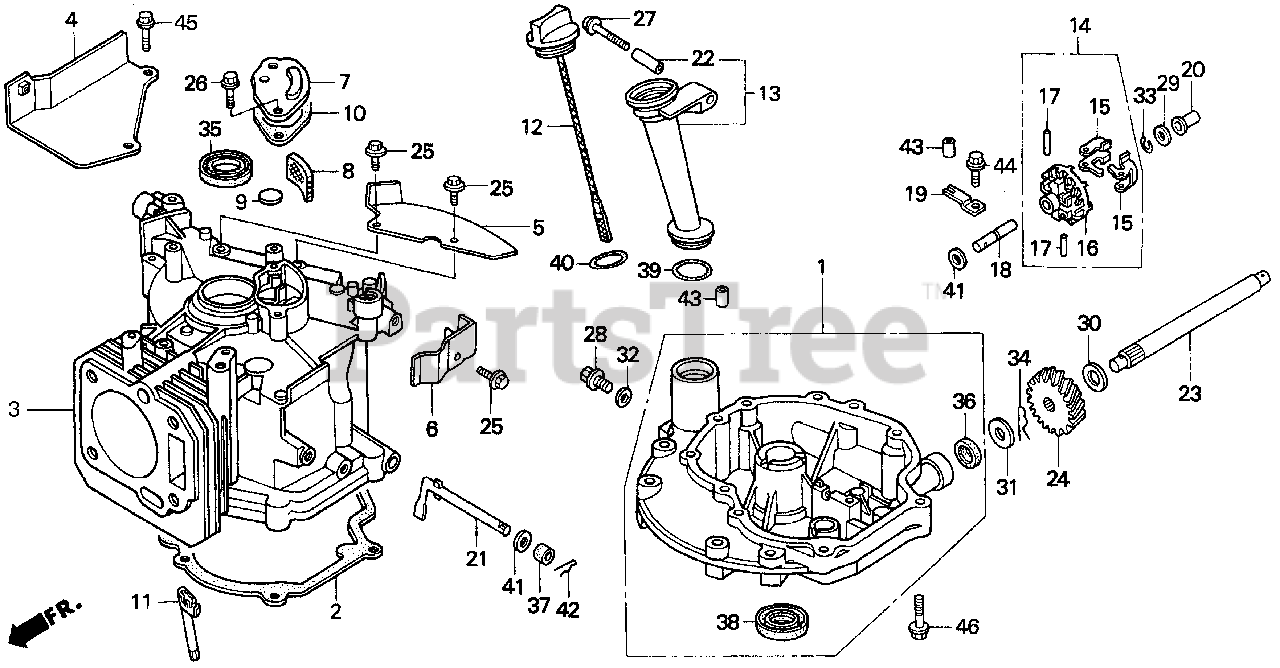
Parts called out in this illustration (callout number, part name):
1	PAN ASSY., OIL
2	GASKET, OIL PAN (HPE)
3	CYLINDER
4	PLATE, GUIDE
5	PLATE A, GUIDE
7	CAP, BREATHER CHAMBER
8	FILTER, BREATHER
9	VALVE, BREATHER
10	GASKET, BREATHER CHAMBER
11	PIPE, OIL DEFENSE
12	DIPSTICK, OIL
13	EXTENSION, OIL FILLER (106MM)
14	GOVERNOR ASSY.
15	WEIGHT, GOVERNOR
16	HOLDER, GOVERNOR WEIGHT
17	PIN, GOVERNOR WEIGHT
18	SHAFT, GOVERNOR HOLDER
19	PLATE, GOVERNOR SHAFT HOLDER
20	SLIDER, GOVERNOR
21	SHAFT, GOVERNOR ARM
22	COLLAR, EXTENSION
25	BOLT, FLANGE (6X12) (CT200)
26	BOLT, FLANGE (6X14)
27	BOLT, FLANGE (6X32)
28	BOLT, DRAIN PLUG
29	WASHER, THRUST (6MM)
32	WASHER, DRAIN PLUG (10.2MM)
33	CLIP, GOVERNOR HOLDER
35	OIL SEAL (22X35X6)
37	OIL SEAL (6X11X4)
38	OIL SEAL (25X38X7)
38	OIL SEAL (25X38X7) (ARAI)
39	O-RING (22.5X2.2)
40	O-RING (26X2.7)
41	WASHER, PLAIN (6MM)
42	PIN, LOCK (8MM)
43	PIN A, DOWEL (8X14)
44	BOLT, FLANGE (6X12)
45	BOLT, FLANGE (6X20)
46	BOLT, FLANGE (6X28)
